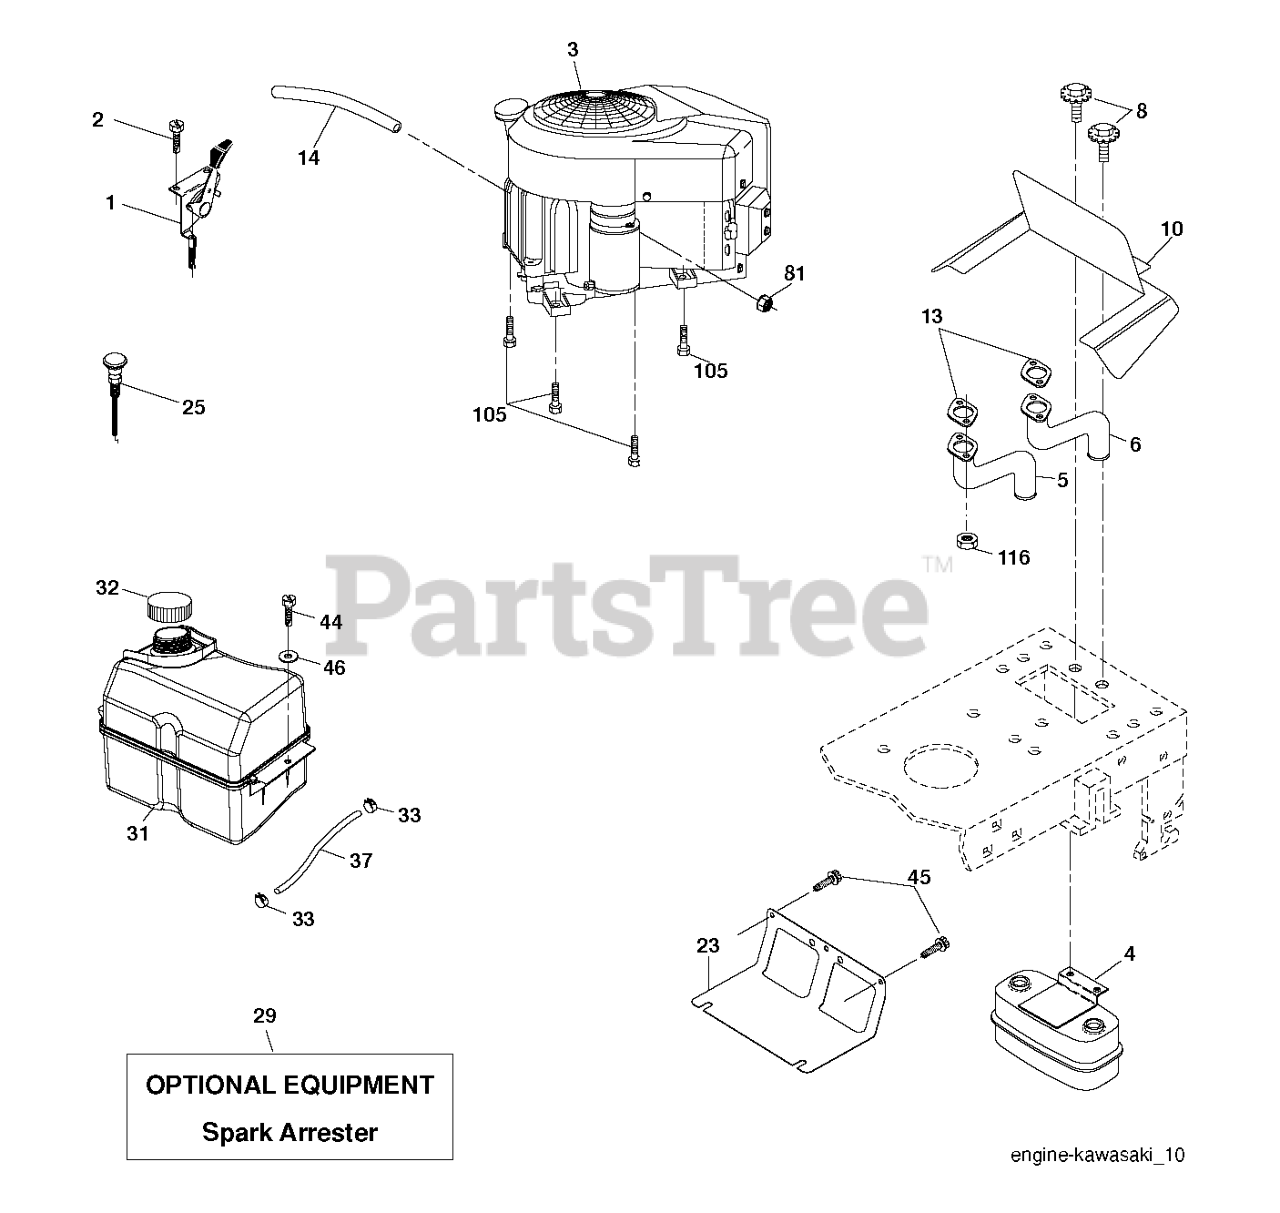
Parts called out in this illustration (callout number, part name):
1	THROTTLE CABLE
2	SCREW.#10 X 0.750.BOS
4	MUFFLER.TWIN.CYL.LOW.TONE
5	EXHAUST TUBE LH KAWI
6	EXHAUST TUBE RH KAWI
8	BOLT.5/16-18UNCX3/4 W/SEMS.BLK
10	RP SHIELD HEAT MUFFLER
13	GASKET.EXHAUST.KAWASAKI.15-1
14	TUBE, DRAIN OIL ASM.
23	SHIELD.BROWNING.DBR.GUARD
25	CONTROL, CHOKE
29	KIT.SPARK ARRESTOR 794945 B&S
31	TANK.ASM.FUEL.FR.2.5GA.
32	FUEL CAP
33	HOSE CLAMP
37	LINE.FUEL.20
44	SCREW HEXWSHR 1/4-20X3/4
45	SCREW, 3/8-16X3/4
81	NUT
105	SCREW 3/8-16X1
116	NUT.HEX.FLANGE.TOPLOCK
